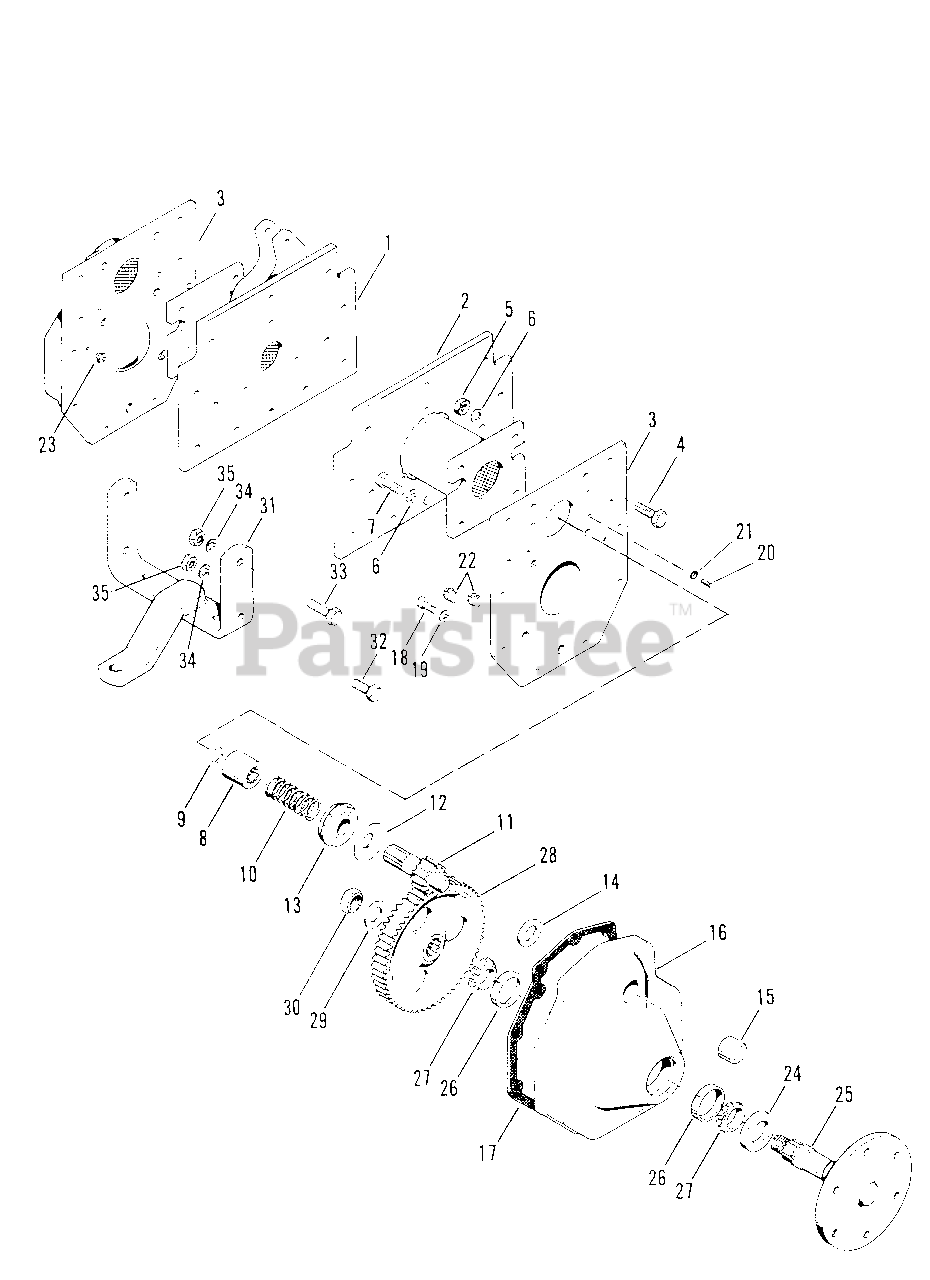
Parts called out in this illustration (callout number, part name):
1	Axle Extension, L.H.
2	Axle Extension, R.H.
3	Housing Plate
4	Hex Capscrew, 1/2"-13 x 1-1/2" lg.
5	Hex Nut, Full, 1/2"-13
6	Locks Washer, 1/2"
7	Hex Capscrew, 1/2"-13 x 1" lg.
8	Axle Coupe
9	Retaining Ring
11	Bull Pinion
13	Rear Axle Bearing
14	Thrust Washer
15	Roller Bearing
16	Drop Housing
18	Hex Capscrew,
19	Lock Washer, 3/11"
22	Pipe Plug
23	Relief Valve
25	Rear Axle Assembly
26	Bearing Cup
27	Bearing Cone
28	Bull Gear
29	Plain Washer
30	Flex Lock Nut
32	Hex Capscrew, 1/2"-13 x 1-1/2" lg.
33	Hex Capscrew, 1/2"-13 x 2" lg.
34	Lock Washer, 1/2"
35	Hex Nut, 1/2"-13
